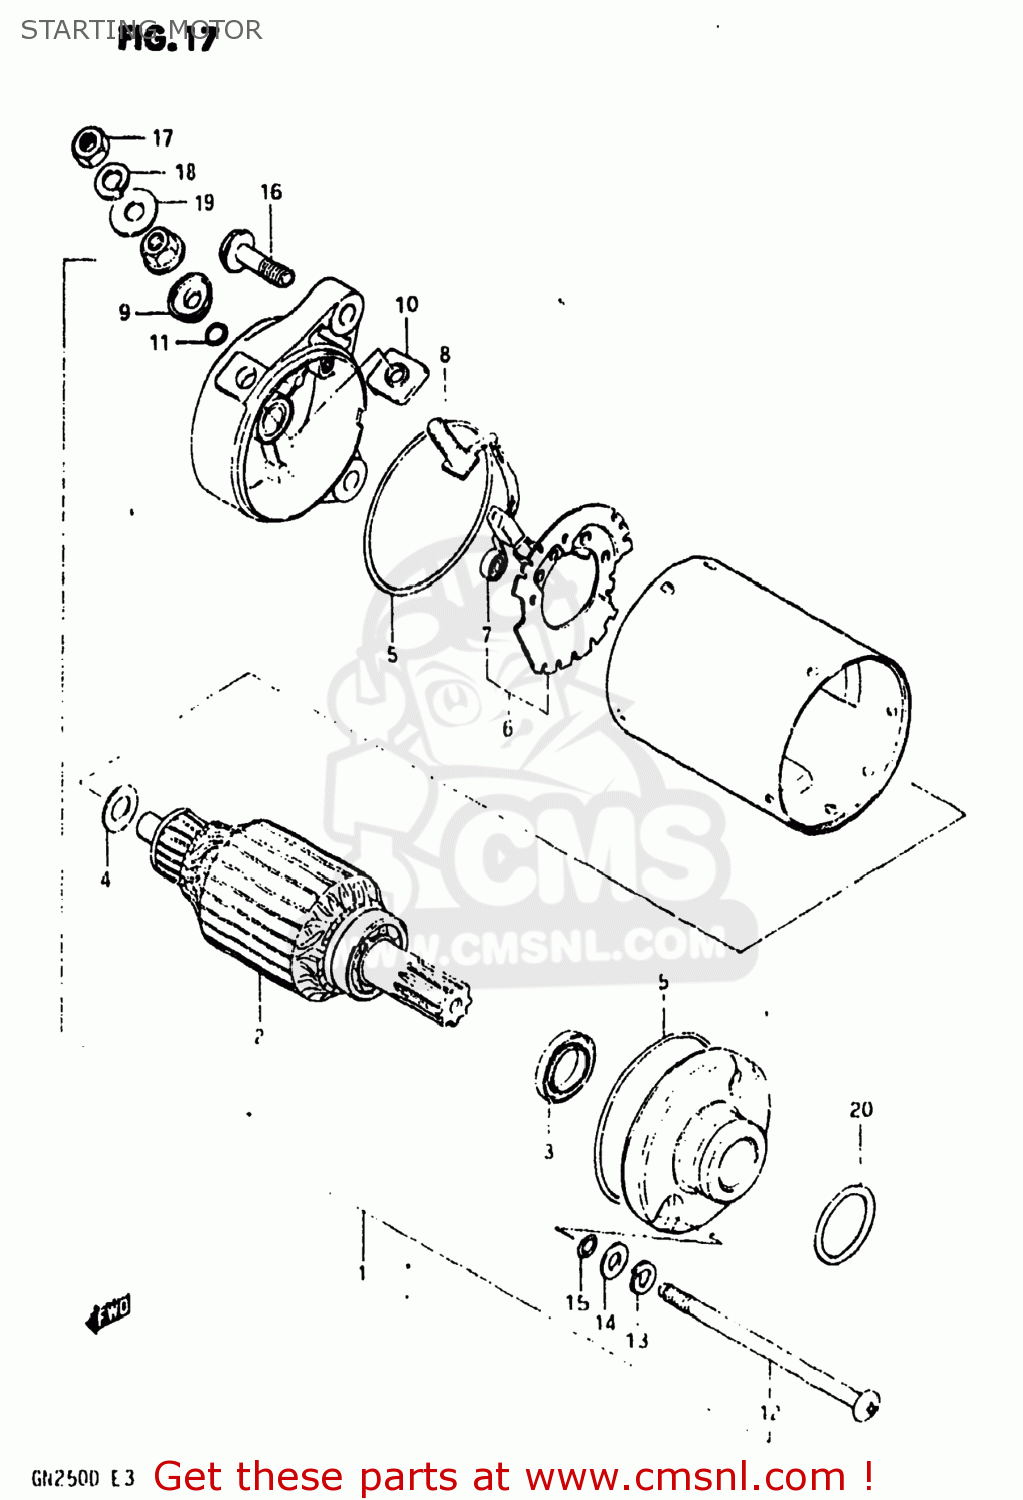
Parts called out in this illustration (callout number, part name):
1	MOTOR ASSEMBLY,STARTING
2	ARMATURE
3	SEAL,OIL
4	SHIM,ARMATURE
5	O RING
6	HOLDER,BRUSH
7	SPRING
8	BRUSH SUB ASSY,STARTING MOTOR
9	BUSHING
10	BUSH,B
11	O RING
12	BOLT
13	LOCK WASHER
14	WASHER
15	O RING
16	BOLT
17	NUT 6MM
18	LOCK WASHER
19	WASHER (6.7X16X1.8)
20	O RING(D:2,ID:24.5)
